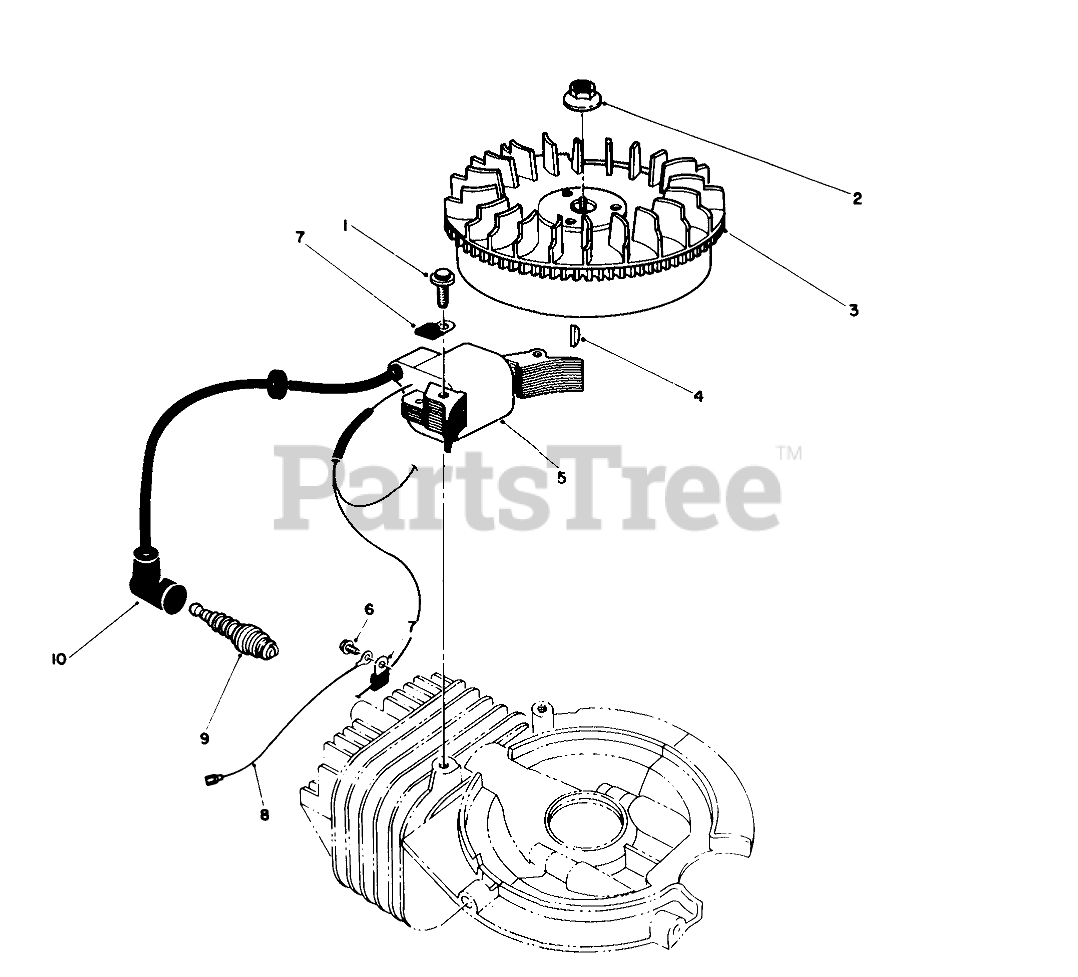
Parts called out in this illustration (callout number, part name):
1	SCREW
3	FLYWHEEL
7	CLAMP
9	Sparkplug
10	CAP-SPARKPLUG
